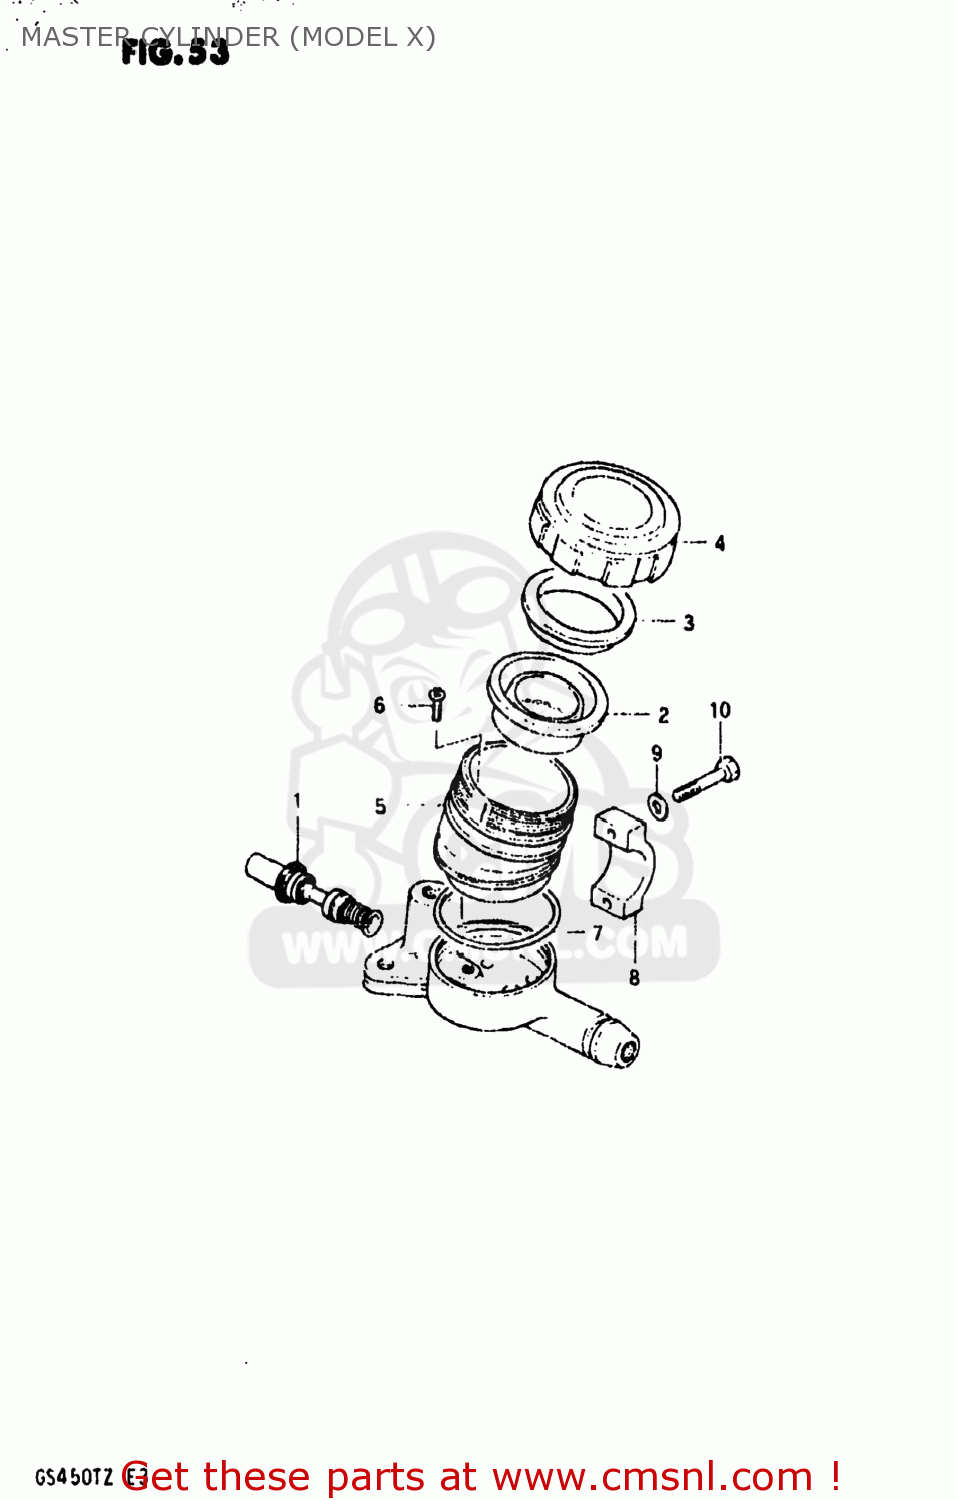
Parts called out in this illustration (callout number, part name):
1	PISTON & CUP SET
2	DIAPHRAGM
3	PLATE,DIAPHRAGM
4	CAP
5	RESERVOIR
6	SCREW,MASTER CYLINDER
7	O RING
8	HOLDER,MASTER CYLINDER
9	WASHER
10	BOLT
